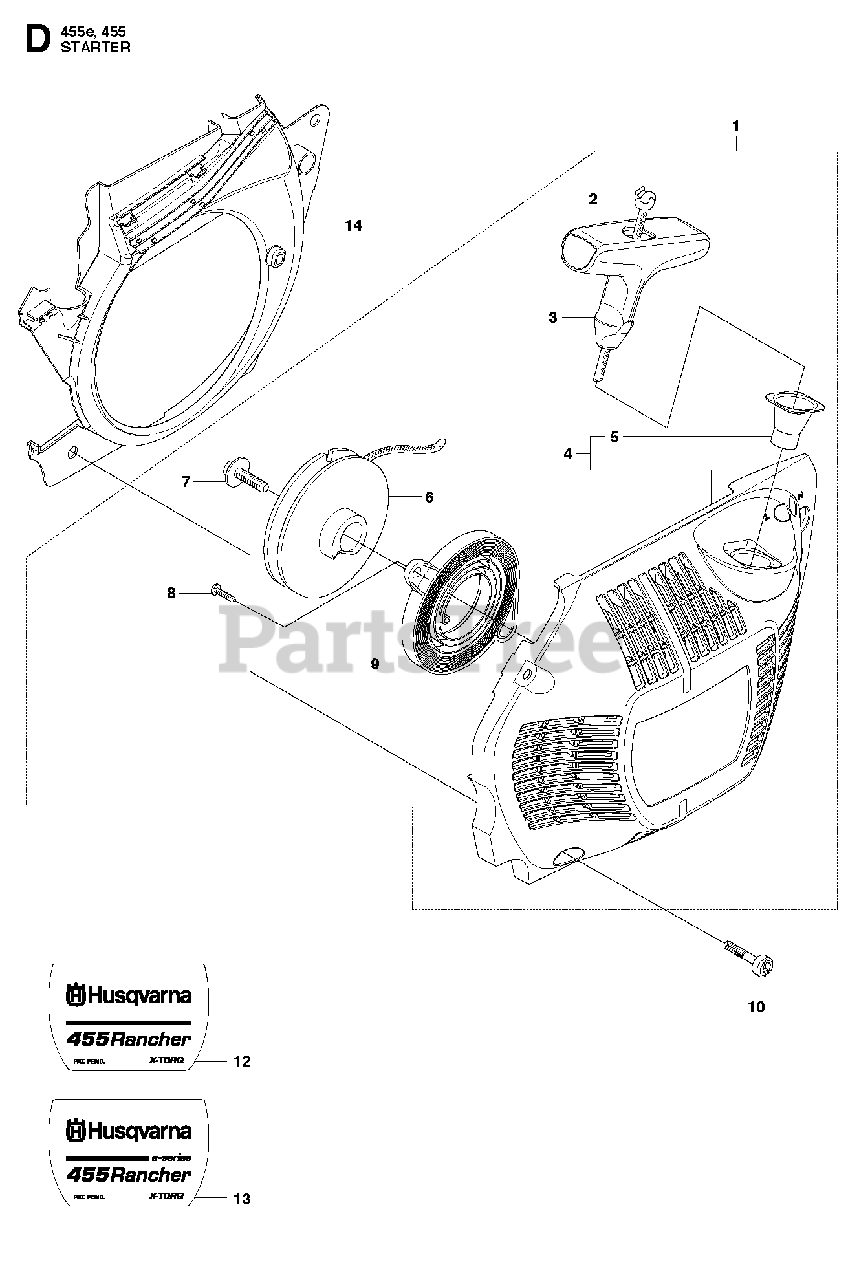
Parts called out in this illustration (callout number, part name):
1	STARTER HOUSING CPL.
2	STARTER ROPE
3	HANDLE
4	STARTER HOUSING
5	SLEEVE
6	PULLEY
7	SCREW
8	SCREW
9	RETURN SPRING
13	DECAL, STARTER
14	AIR CONDUCTOR
